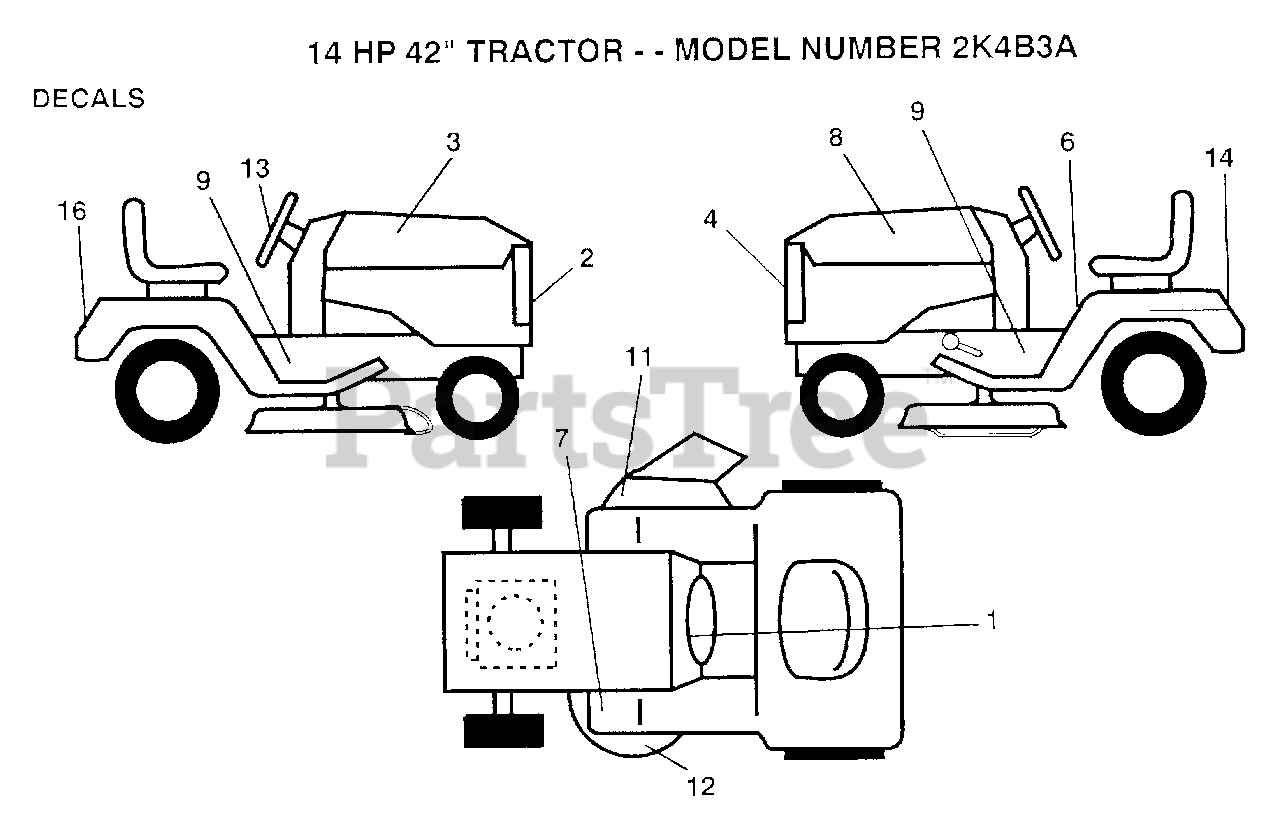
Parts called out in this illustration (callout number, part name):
2	GRILL DECAL
6	DECAL CAUTION
7	DECAL T
9	CHASSIS DECAL
11	"DECAL, WARNING"
13	"DECAL,STR WHL"
14	DECAL
16	FENDER DECAL
